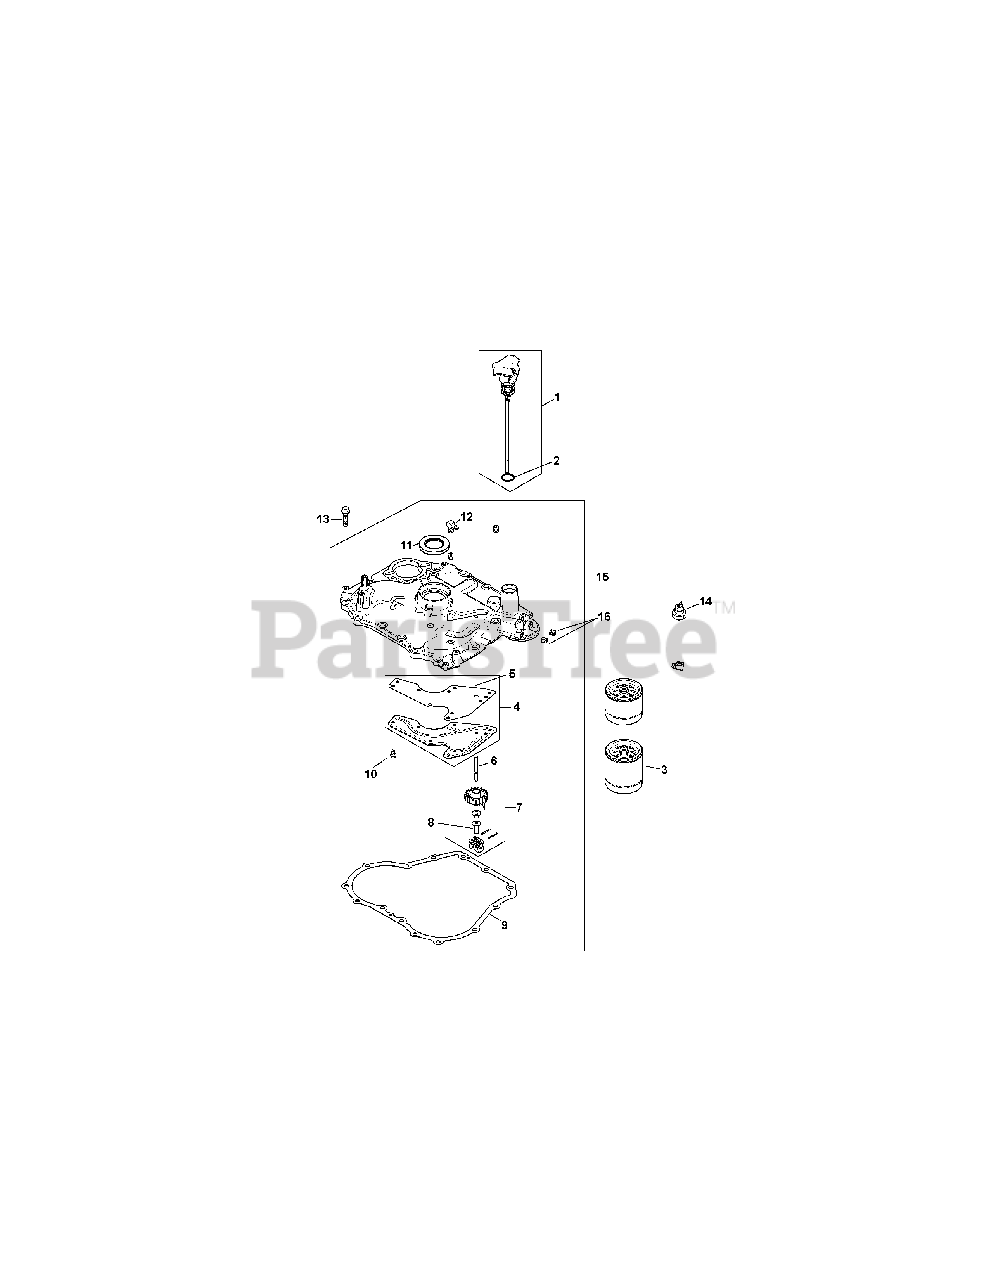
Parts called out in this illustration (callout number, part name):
1	Dipstick Assembly (Inc. 2)
4	Oil Passage Cover Kit (Inc. 5)
5	Oil Passage Gasket
6	Governor Cross Shaft
7	Governor Gear Assembly
8	Governor Regulating Pin
9	Closure Plate Gasket
10	Screw, hex. flange thrd forming 5x.8x13
12	90° Hose Connector
13	Hex Flange Screw, 1/2
14	Oil Pressure Switch
15	Closure Plate Assembly Kit
16	Ctsk. Pipe Plug, 1/8
